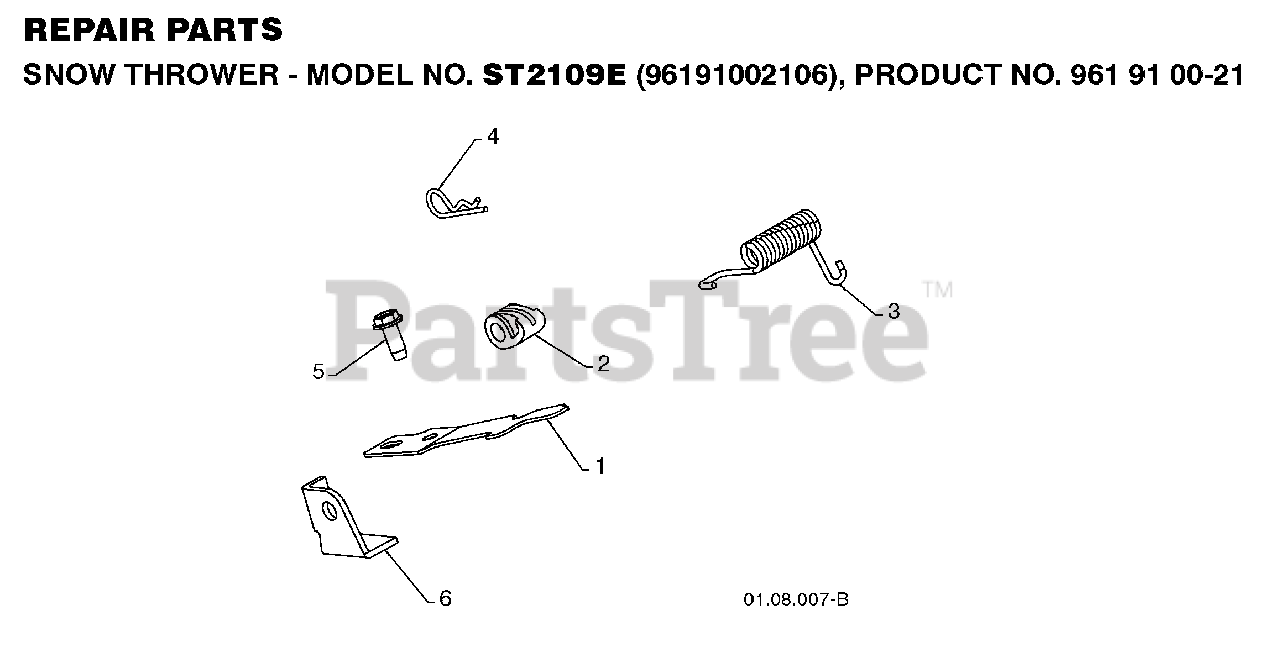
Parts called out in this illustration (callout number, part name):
1	SPRING.INTERLOCK
2	RP CAM.INTERLOCK.RELEASE
3	RP SPRING, TORSION
4	SPRING RETAINER
5	SCREW 14-20 X 5/8
6	STOP.INTERTLOCK
